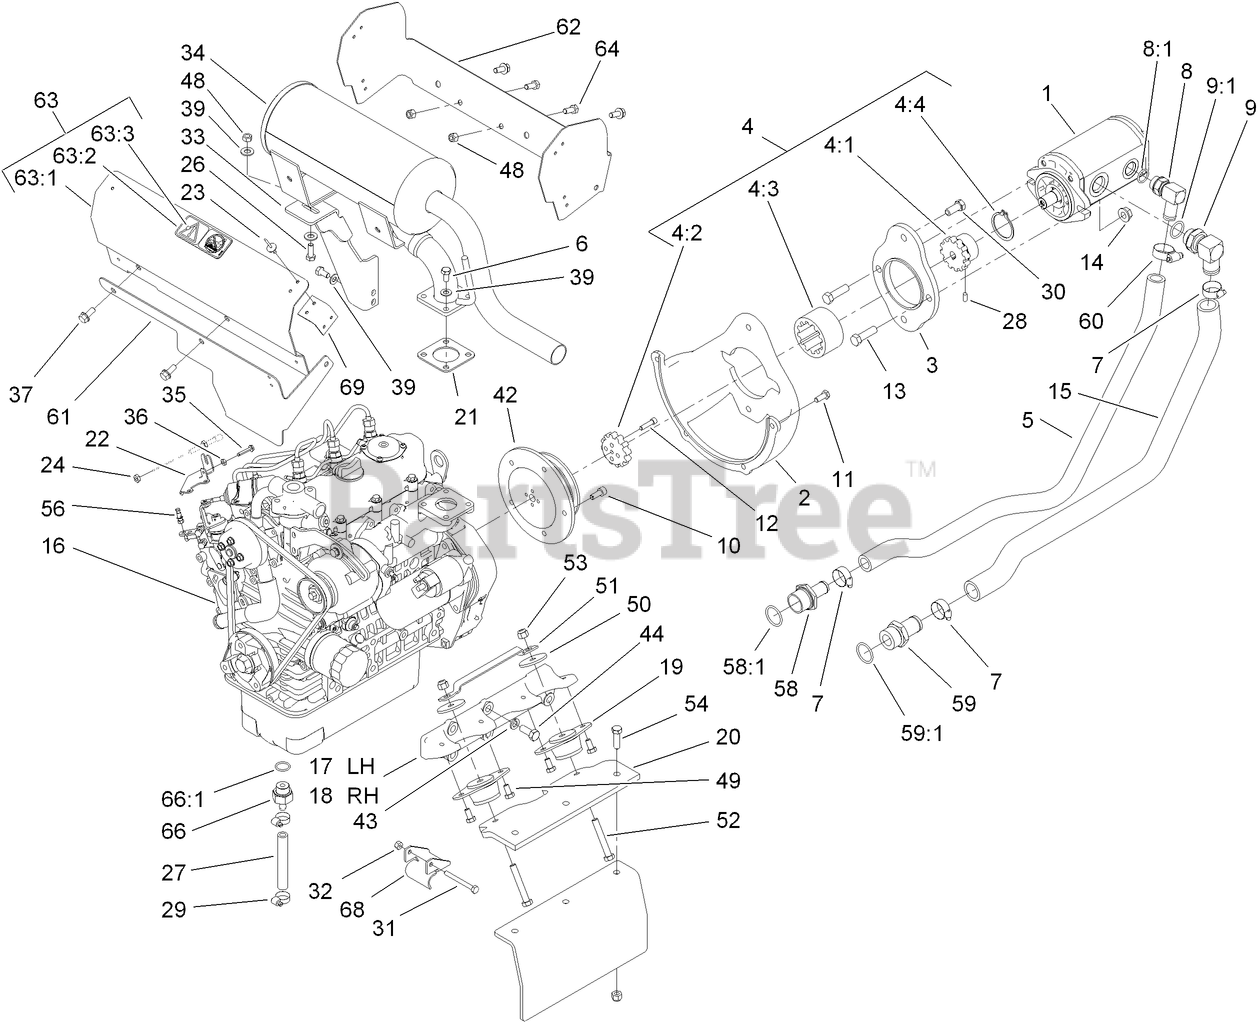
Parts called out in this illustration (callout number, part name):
1	PUMP-HYD
2	PUMP-MOUNT
3	PLATE-MOUNT, PUMP
4	COUPLING ASM
4:1	HUB-COUPLING
4:2	SLEEVE-HUB
4:3	SLEEVE-COUPLING
4:4	RING-SNAP, COUPLING
5	HOSE-FORMED, SUCTION
6	BOLT
7	CLAMP-HOSE
8	FITTING
8:1	O-RING
9	FITTING-HYD, 90 DEG
9:1	O-RING
10	SCREW-CAP, HSH
11	SCREW-HH
12	SCREW-HSH
13	SCREW-HH
14	NUT-HF
15	HOSE-FORMED, SUCTION
16	ENGINE-KUBOTA, D902
17	MOUNT-ENGINE, LH
18	MOUNT-ENGINE, RH
19	MOUNT-ENGINE
20	PLATE-MOUNT, ENGINE
21	GASKET-MUFFLER
22	BRACKET-SUPPORT, THROTTLE
23	RIVET
24	NUT-JAM
26	SCREW-HH
27	HOSE-DRAIN, ENGINE OIL
28	SCREW-SET, HSH
29	CLAMP-HOSE
30	SCREW-HH
31	SCREW-HH
32	NUT-LOCK, CONE
33	SUPPORT-MUFFLER
34	MUFFLER ASM
35	SCREW-HWHTF
36	NUT-HEX
37	SCREW-HHF
39	WASHER-PLAIN
42	PULLEY-MACHINED
43	WASHER-LOCK, SPRING
44	SCREW-HH
48	NUT-LOCK, CONE
49	SCREW-HH
50	WASHER-REBOUND
51	STRAP-REBOUND
52	SCREW-HH
53	NUT-LOCK, NI
54	SCREW-HH
56	SWIVEL-STOP, CABLE
58	FITTING-HOSE, BARBED
58:1	O-RING
59	FITTING-STR
59:1	O-RING
60	CLAMP-HOSE
61	PLATE-BAFFLE, LOWER
62	PLATE-BAFFLE
63	HEAT SHIELD BAFFLE ASM
63:1	PLATE-BAFFLE, MUFFLER
63:2	PLATE-HOT SURFACE
63:3	RIVET-POP
64	SCREW-HH
66	FITTING-HOSE
66:1	GASKET
68	GUIDE-CABLE
69	BRACKET-SHIELD
